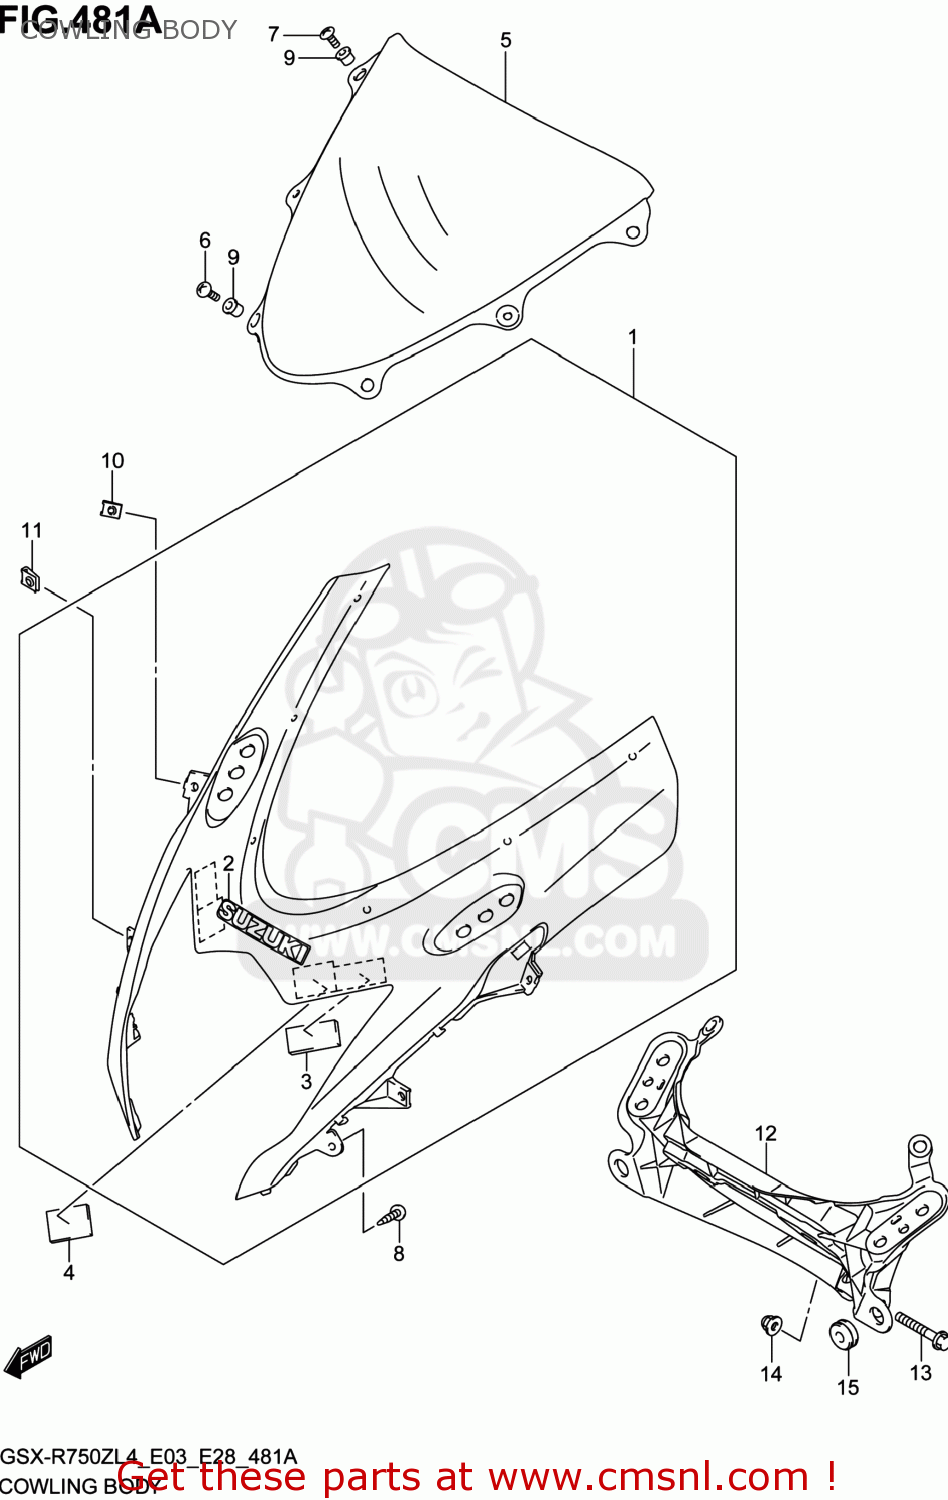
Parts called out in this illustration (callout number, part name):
1	COWLING,BODY(RED)
2	EMBLEM,SUZUKI
3	CUSHION,BODY COWLING
4	FASTENER
5	WINDSCREEN
6	SCREW(5X18)
7	SCREW(5X15)
8	SCREW
9	NUT
10	NUT
11	NUT
12	BRACE,COWLING
13	BOLT(8X45)
14	NUT
15	CUSHION
